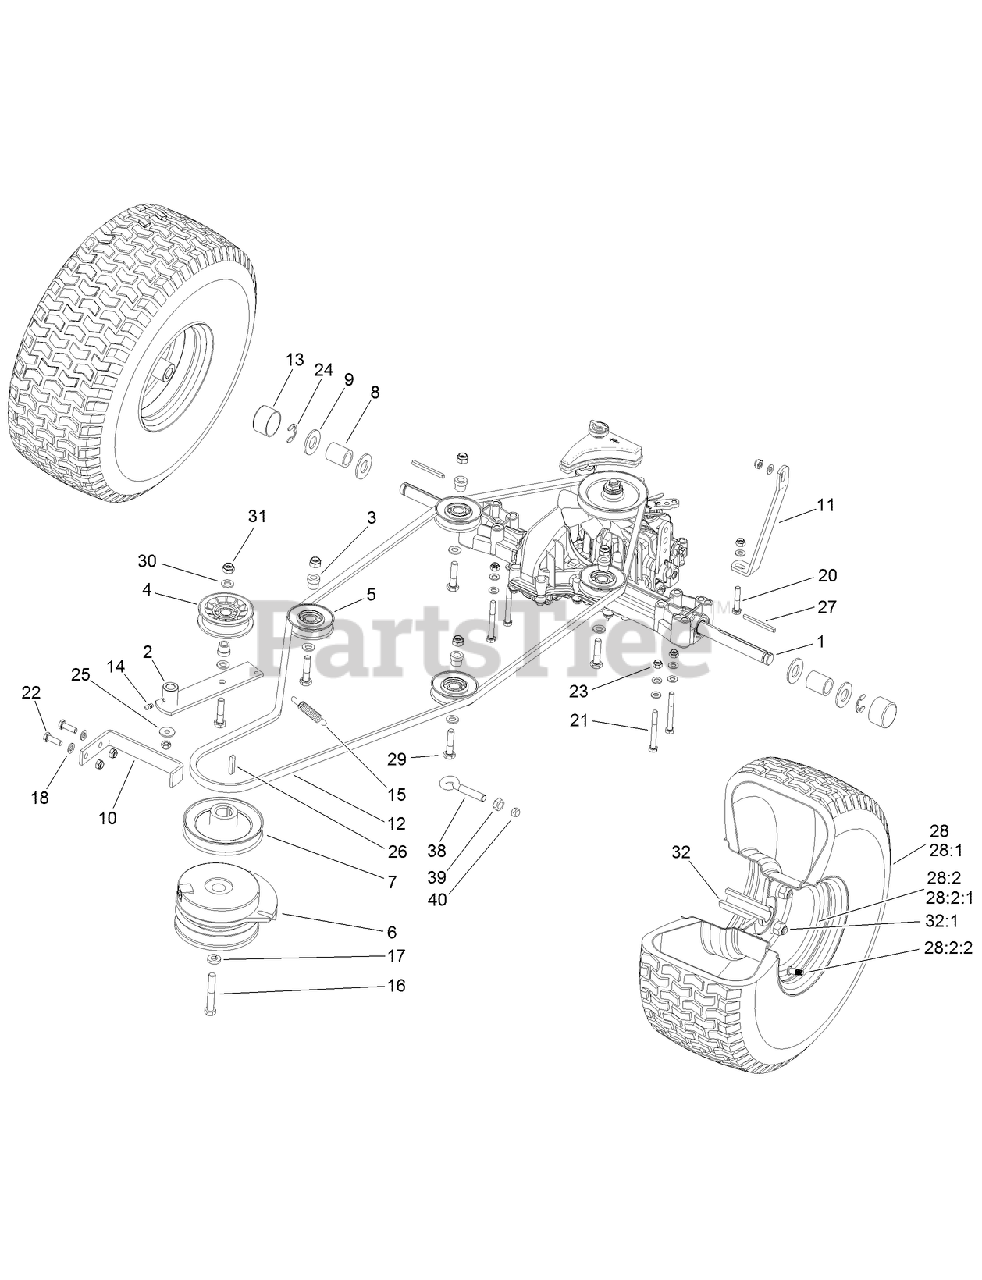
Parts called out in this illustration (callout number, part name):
1	TRANSMISSION
2	ARM-IDLER
3	BUSHING-IDLER
4	PULLEY-IDLER
5	PULLEY-IDLER
6	CLUTCH-ELECTRIC
7	PULLEY-ENGINE
8	SPACER-AXLE
9	WASHER
10	RETAINER
11	STABILIZER
12	BELT-TRANSMISSION, HEAVY DUTY
13	CAP-HUB
14	FITTING-GREASE
15	SPRING
16	SCREW-HH
17	WASHER-SPRING, BELLEVILLE
18	WASHER-PLAIN
20	SCREW-HH
22	SCREW-HH
23	NUT-LOCK, NI
24	CLIP-SPRING
25	WASHER-PLAIN
26	KEY-SQUARE
27	KEY-SQUARE
28	TIRE AND WHEEL ASM
28:2	WHEEL ASM
28:2:1	Loose Parts Package
28:2:2	Valve-Tire
29	SCREW-HH
30	WASHER-FLAT
31	NUT-LOCK, NI
32	HUB-WHEEL
32:1	NUT-LUG
38	SCREW-EYELET
39	NUT-HEX
40	NUT-LOCK
